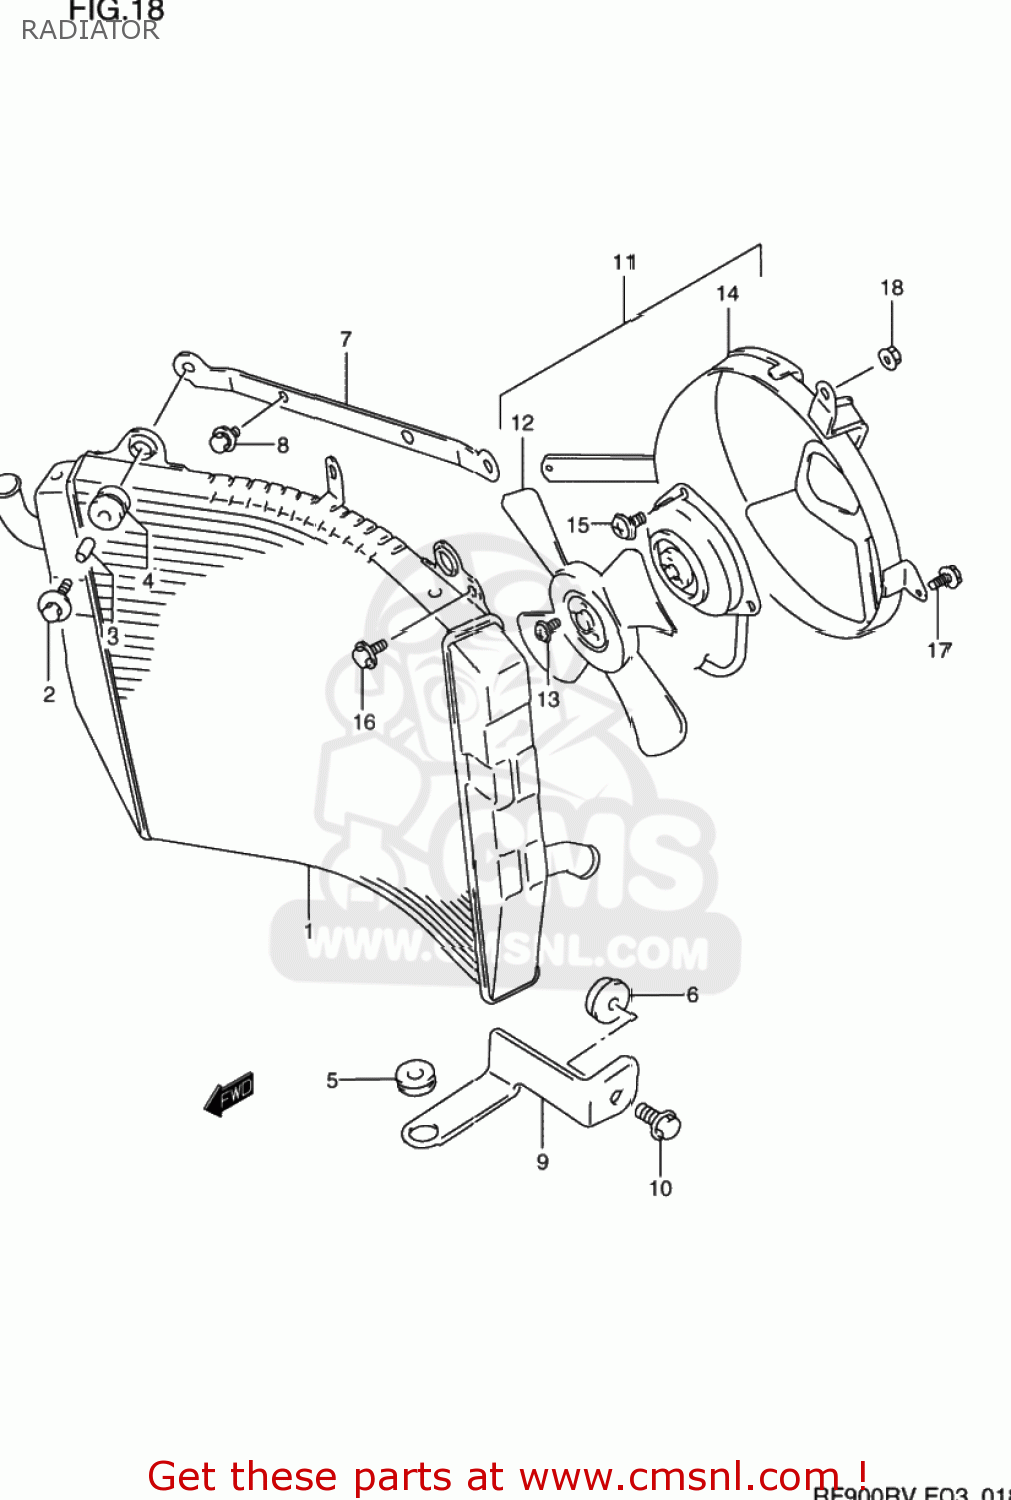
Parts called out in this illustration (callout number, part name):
1	RADIATOR ASSY,WATER
2	BOLT(6X25)
3	SPACER(6.5X10.5X12)
4	CUSHION,RADIATOR LWR
5	CUSHION
6	SPACER,RADIATOR BRACKET LWR
7	BRACKET COMP,RADIATOR
8	BOLT
9	BRACKET COMP,RADIATOR
10	BOLT
11	FAN ASSY,RADIATOR
12	FAN
13	SCREW 4X6
14	SHROUD ASSY,FAN
15	SCREW
16	BOLT
17	BOLT
18	NUT
